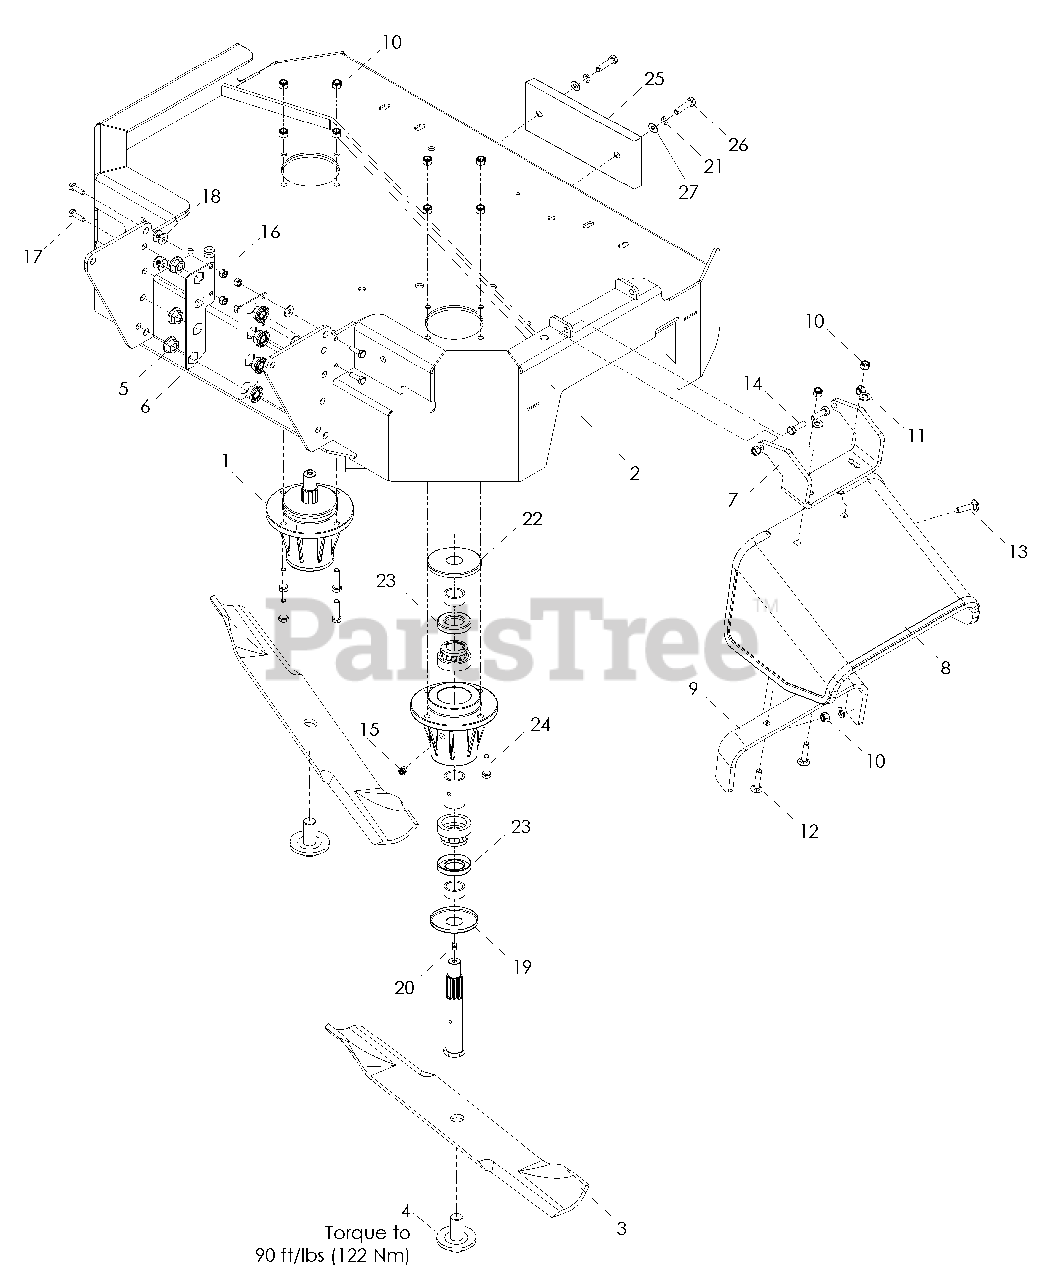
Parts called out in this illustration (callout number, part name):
1	SPINDLE ASSEM
2	DECK W DECALS, 36"
3	BLADE, 18"
4	BOLT, BLADE
5	NUT, FLANGE, 1/2-13
6	NUT, PLATE
7	HINGE, CHUTE
8	RUBBER CHUTE
9	REINFORCEMENT, BRKT
10	NUT 5/16-18 HEX NYLOC
11	WASHER 5/16 SAE FLAT
12	RHSNB 5/16-18 x 1 1/4
13	RHSNB 5/16-18 x 1 1/4
14	HCS 5/16-18 x 1
15	GREASE POPPET
16	NUT 1/4-20 HEX NYLOC
17	HCS 1/4-20 x 7/8
18	WASHER 1/4 FLAT
19	DUST CAP, BOTTOM
21	WASHER 1/2 SLW
22	DUST CAP, TOP
23	SEAL, SHAFT
24	HCS 5/16-18 x 1 1/4
25	WEIGHT, COUNTER
26	HCS 1/2-13 x 1 1/2
27	WASHER 1/2 SAE FLAT
